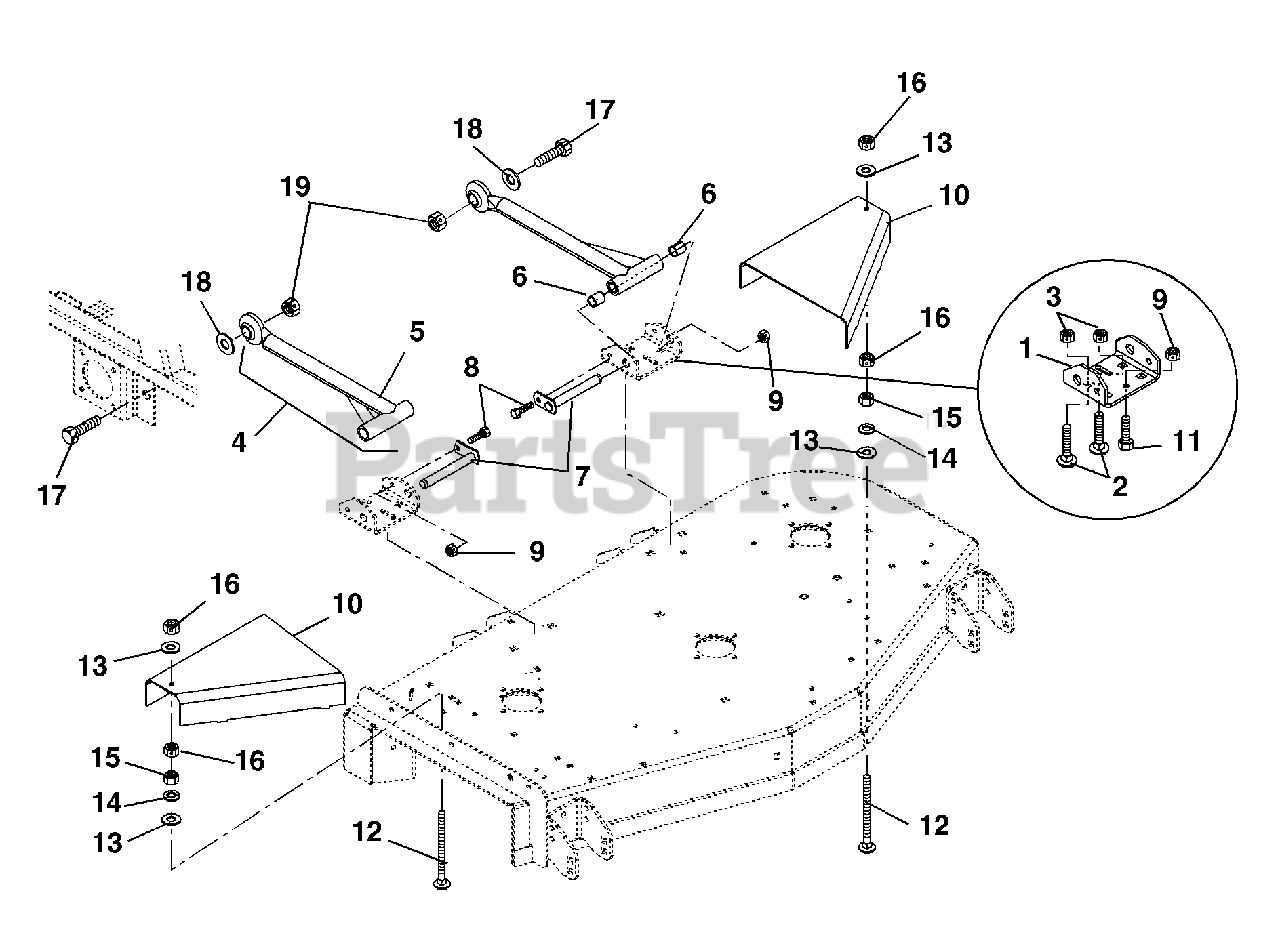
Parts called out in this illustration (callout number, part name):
1	Bracket, Mower Mounting (Rear)
2	Bolt, Round Head Square Neck .50-13 x .75 Grade 5
3	Nut, Locking Center Jam .50-13
4	Assembly, Mower Mounting Arm
5	Weldment, Mower Mounting Arm
6	Bearing .75 x .875 x 1.00
7	Weldment, Mower Mounting Pin
8	Bolt, Hex .38-16 x 1.00 Grade 5
9	Nut, Locking Top Flange .38-16
10	Guard, Pulley Left Hand (058, 060, 318, 319)
10	Guard, Pulley Right Hand (058, 060, 318, 319)
10	Guard, Right Hand Pulley (059, 061)
10	Guard, Left Hand Pulley (059, 061)
11	Bolt, Round Head Square Neck .38-16 x .75 Grade 5
12	Bolt, Round Head Square Neck Full Thread .312-18 x 3.50 (058, 060, 318, 319)
12	Bolt, Round Head Square Neck Full Thread .312-18 x 3.50 (059, 061)
13	Washer, Flat Steel .344 x .688 x .06 (058, 060, 318, 319)
13	Washer, Flat Steel .344 x .688 x .065 (059, 061)
14	Washer, Locking .31 x .078 (058, 060, 318, 319)
14	Washer, Locking .31 x .078 (059, 061)
15	Nut, Hex .31-18 (058, 060, 318, 319)
15	Nut, Hex .31-18 (059, 061)
16	Nut, Locking Center .31-18 (058, 060, 318, 319)
16	Nut, Locking Center .31-18 (059, 061)
17	Bolt, Hex .875-9 x 2.75 Grade 5
18	Washer, Flat Steel .875 x 1.50 x .120
19	Nut, Locking Center .875-9
